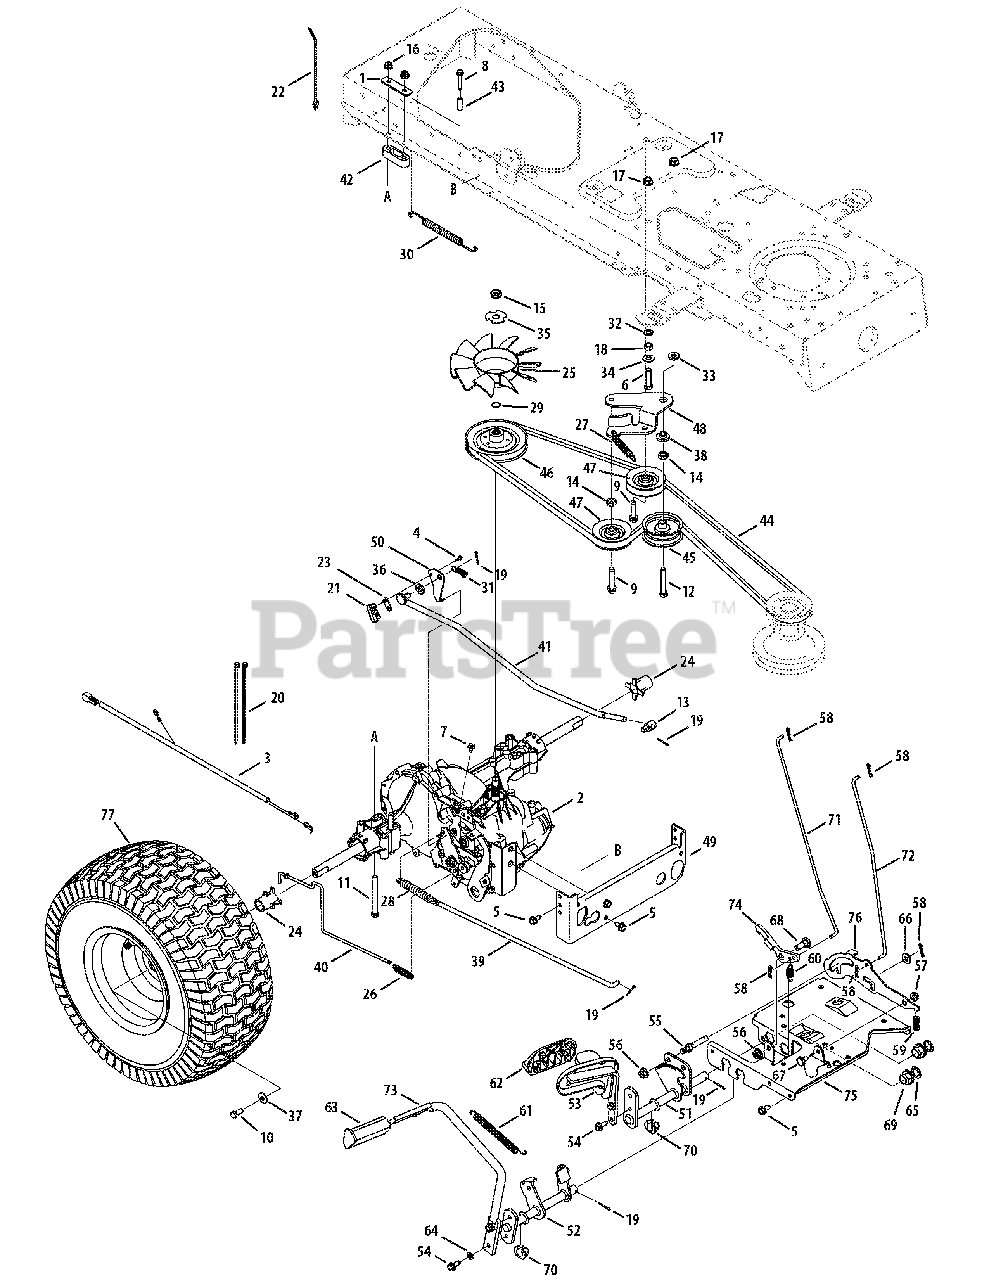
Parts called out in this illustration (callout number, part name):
2	Hydrostatic Transmission, 0510
3	Hydro Ground Harness Assembly
4	Screw, #8-18 x 0.500
5	Self-Tap Screw, 5/16-18 x .750
6	Hex Head Screw, 3/8-16 x 1.50 Gr5
7	Self-Tap Screw, 1/4-20 x 0.375
8	Self-Tap Screw, 1/4-20 x 1.500
9	Sems Self-Tap Screw, 3/8-16 x 1.500
10	Hex Head Screw, 5/16-24, .750 x Gr5
11	Hex Head Screw, 5/16-18 x 3.50 Gr5
12	Hex Head Screw, 3/8-16 x 2.25
13	Ferrule, 3/8-24 x .375
14	Jam Nut, 7/16-20
15	Flange Jam Nut, 1/2-20 Gr5
16	Flange Lock Nut, 5/16-18 Grf
17	Flange Lock Nut, 3/8-16 Grf
18	Hex Nut, 3/8-16 Gr5
19	Cotter Pin, 3/32 1.0
20	Cable Tie, 3/16 X .05 X 7.4
21	Short Spring Switch
22	Push Mount Cable Tie, 7.5 Lg
23	Insulator Plate Nut
24	Sleeve, .765 Id X 1.500 Lg
25	LT Hydro Fan
26	Extension Spring, .48 Od X 2.03
27	Extension Spring, .770 X 3.720 Lg
28	Extension Spring, .59 Od X 4.00 Lg
29	Wire Ring
30	Extension Spring, .500 Dia X 7.0 Lg
31	Extension Spring, 3/8 Od X 1.44 Lg
32	Lock Washer, 3/8 Regular Duty
33	Flat Washer, .385 X 1.0 X .135
34	Flat Washer, .406 X .875 X .059
35	Lock Washer, Hydro Trans.
36	Flat Washer, .407 x .812 x .135
37	Belleville Washer, .340 X .872 X .060
38	Shoulder Spacer, 1.00 X .38 X .38
39	Hydro Brake Rod
40	Hydro Bypass Rod
41	Hydro Control Rod
42	Spacer, T-Axle .68
43	Spacer, .260 X .372 X 1.030 Lg
44	V-Belt, 4l X 78 Lg Poly
45	Flat Idler Pulley, 2.75 Od
46	Input Pulley, 4.13 Dia
47	Idler Pulley, V-Type X 3.06
54	Self-tap Screw, 5/16-18 x 0.750
55	Pin, 3/8-16 X 2.68lg
56	Flange Lock Nut, 3/8-16 Grf
57	Flange Lock Nut, 5/16-18 Gr5
58	Cotter Pin, .072 Dia. X 1.13 Lg
59	Compression Spring, .405 X 1.17
60	Extension Spring, .50 Od X 1.41 Lg
61	Extension Spring, .50 Dia X 6.37 Lg
62	Drive Pedal Pad
63	Brake Control Pad
64	Lock Washer, 5/16, Regular Duty
65	Flat Washer, .64 X 1.24 X .06
66	Flat Washer, .385 X .870 X .092
67	Shoulder Bolt, .435 X .160, 5/16-18
68	Shoulder Bolt, .500 X .270, 3/8-16
69	Hex Flange Bearing
70	Hex Flange Bearing
71	Brake Lock-Rod
72	Cruise Control Rod
74	Latch, cruise
76	Hydro Lockout Bracket
